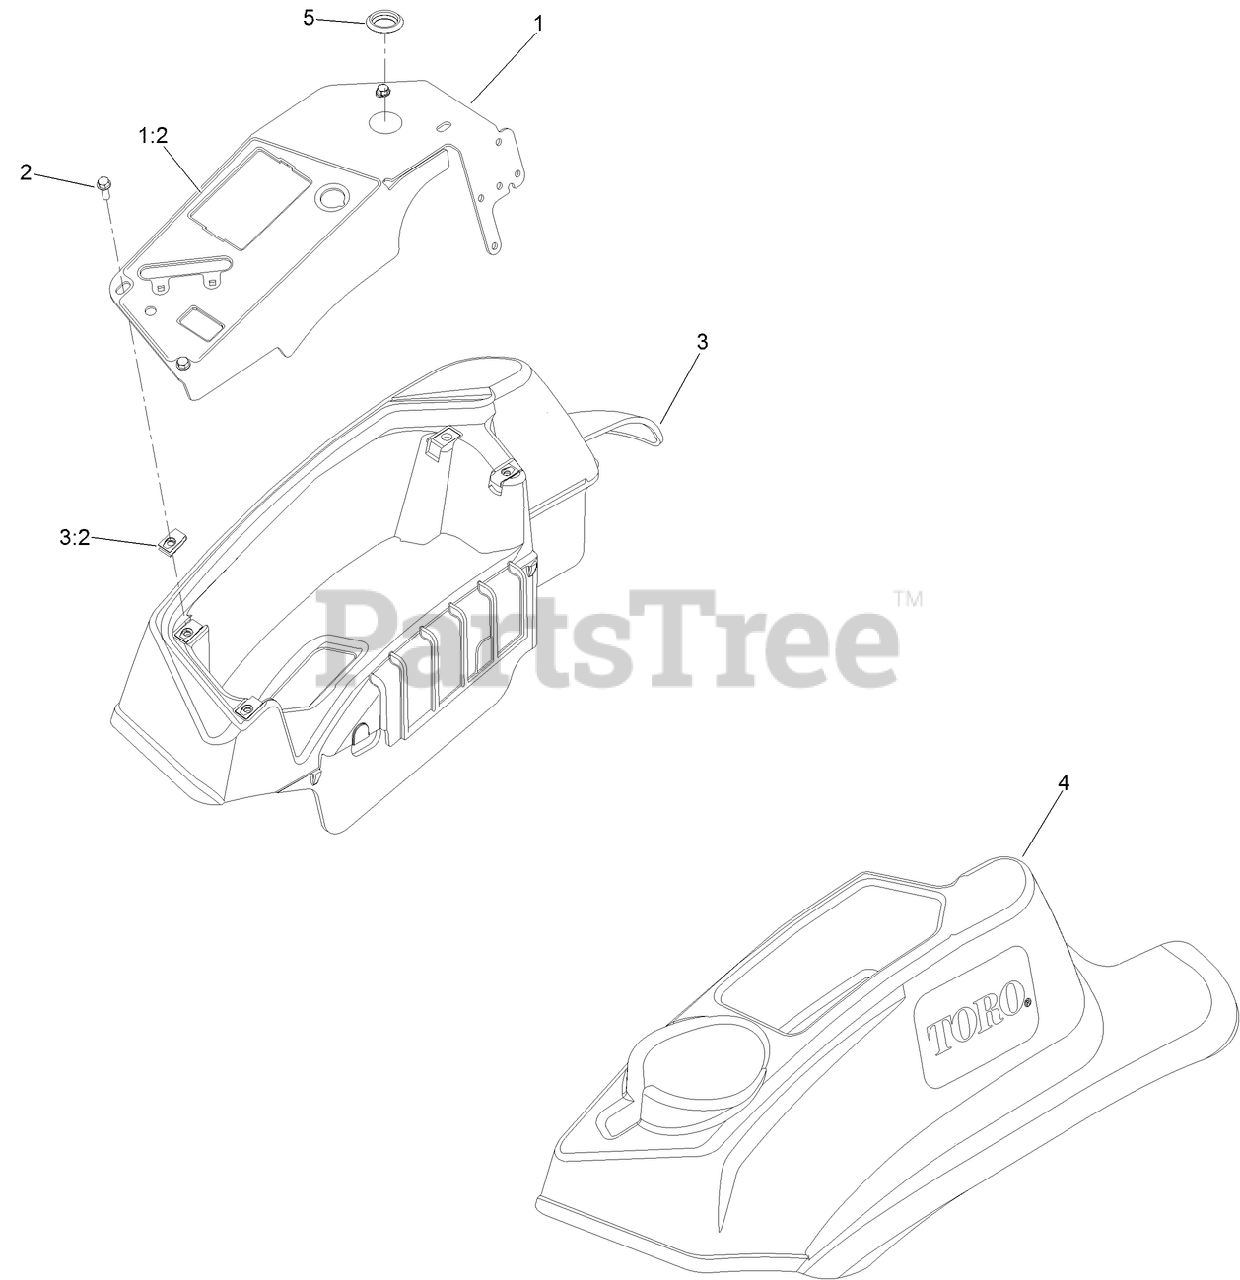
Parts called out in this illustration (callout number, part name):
1	CONTROL PANEL ASM
1:2	DECAL-PANEL, CONTROL
2	SCREW-HWH
3	RH CONSOLE ASM
4	CONSOLE-LH
5	PLUG-PLASTIC
